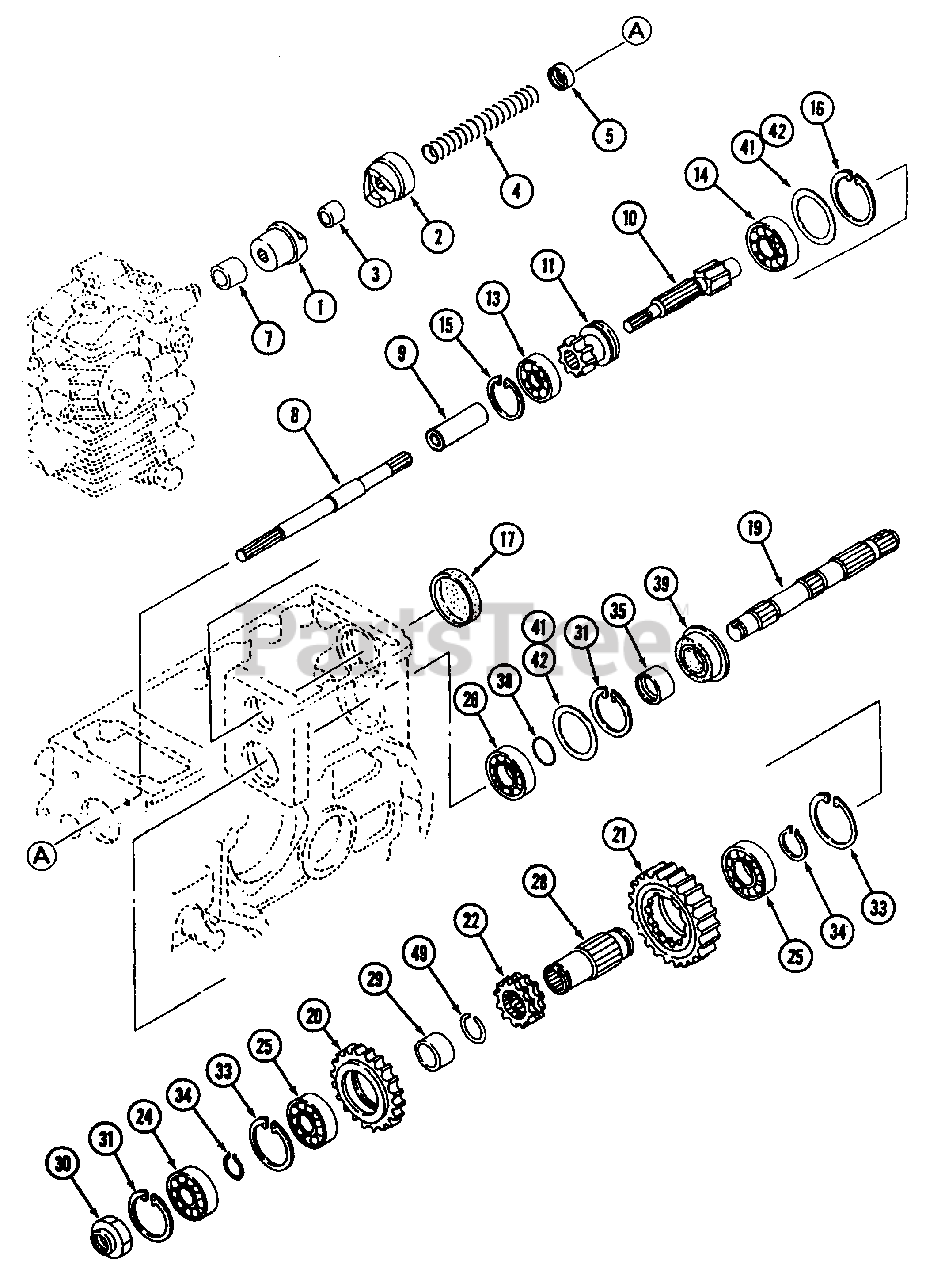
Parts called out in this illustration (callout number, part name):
9	Collar
10	Shaft, PTO Drive
34	Ring
39	Seal, Oil
